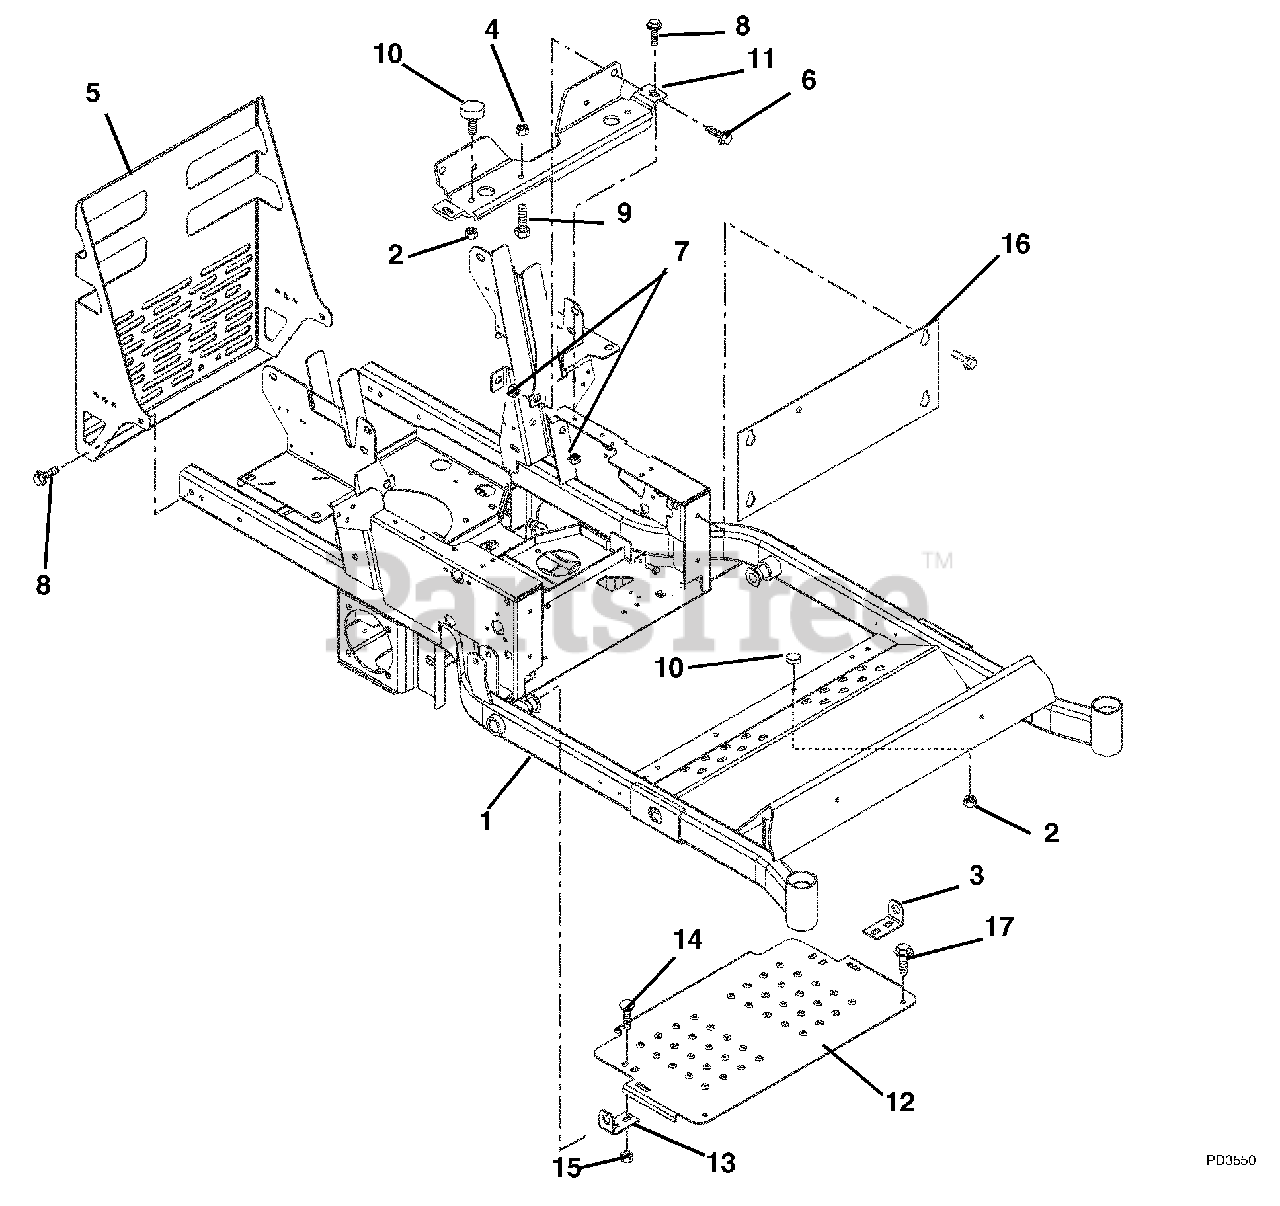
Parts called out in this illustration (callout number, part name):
1	Intermediate Z Frame (042, 043, 044, 054)
1	Intermediate Z Frame (051, 055)
2	Nut-Spin Lock-Flange .312-18
3	Hinge, Footboard Left Hand
4	Nut-Locking-Top-Flange .31-18
5	Bumper/Guard
6	Bolt-Serrated Flange Washer Head .38-16 x 1.00
7	Nut-Retainer .375-16 x .37
8	Screw-Tapping .38-16 x .50 Hex Washer Head
9	Bolt-Hex .31-18 x 1.25 Grade 5
10	Bumper, Rubber
11	Seat Support
12	Footrest Panel
13	Hinge, Footboard Right Hand
14	Bolt-Round Head Square Neck .38-16 x .75 Grade 5
15	Nut-Locking-Top-Flange .38-16
16	Access Panel
17	Screw-Tapping .38-16 x 1.00 Hex Washer Head (310, 311)
